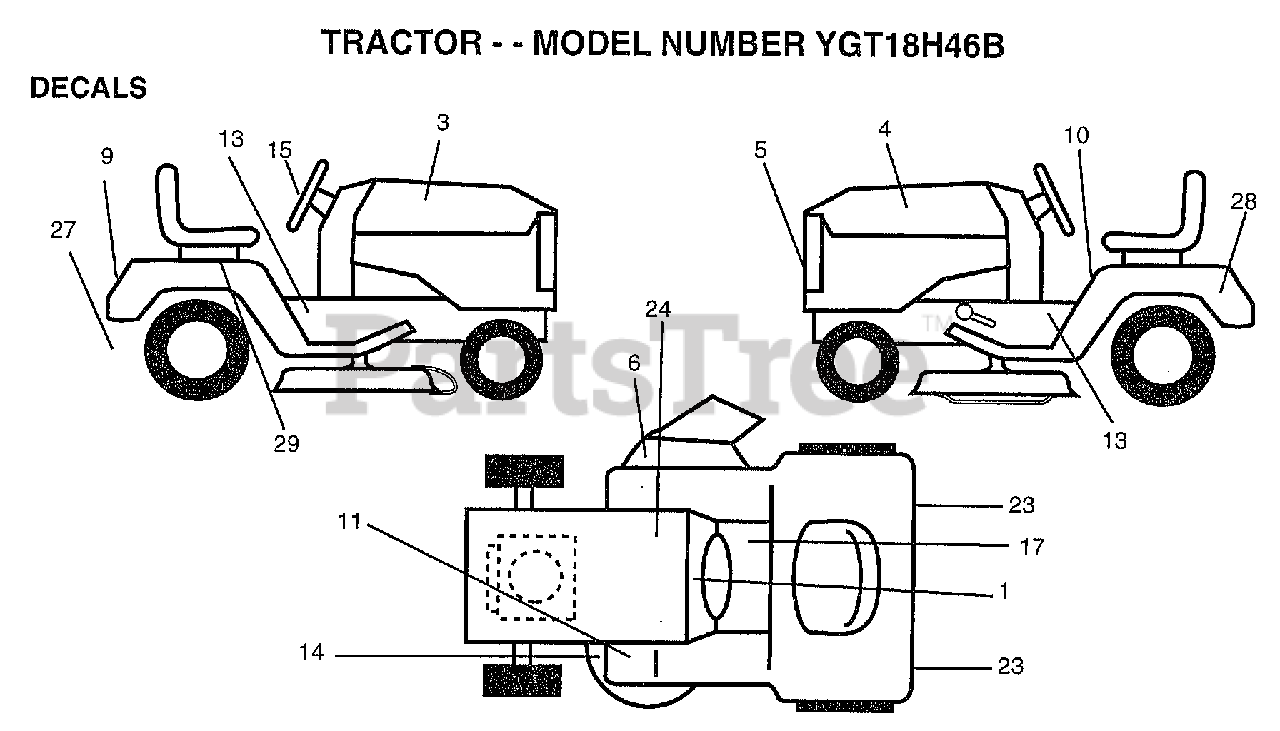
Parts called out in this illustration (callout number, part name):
1	DECAL OPER INSTR.
3	"DECAL HOOD,RH,18H"
4	"DECAL-HOOD,LH,18H"
5	DECAL GRILLE
6	"DECAL, WARNING"
9	DECAL FENDER
10	DECAL.CAUT.ENG/FR
11	DECAL T
13	"DECAL-CHASSIS,46"""
15	DECAL INS STRG WH
17	DECAL BRAK PARK
23	REFLECTOR-TAIL YT
24	DECAL.BATRY.3-3908
27	DECAL D-BAR CNTRL
28	DECAL FENDER LH
29	DECAL FENDER RH
